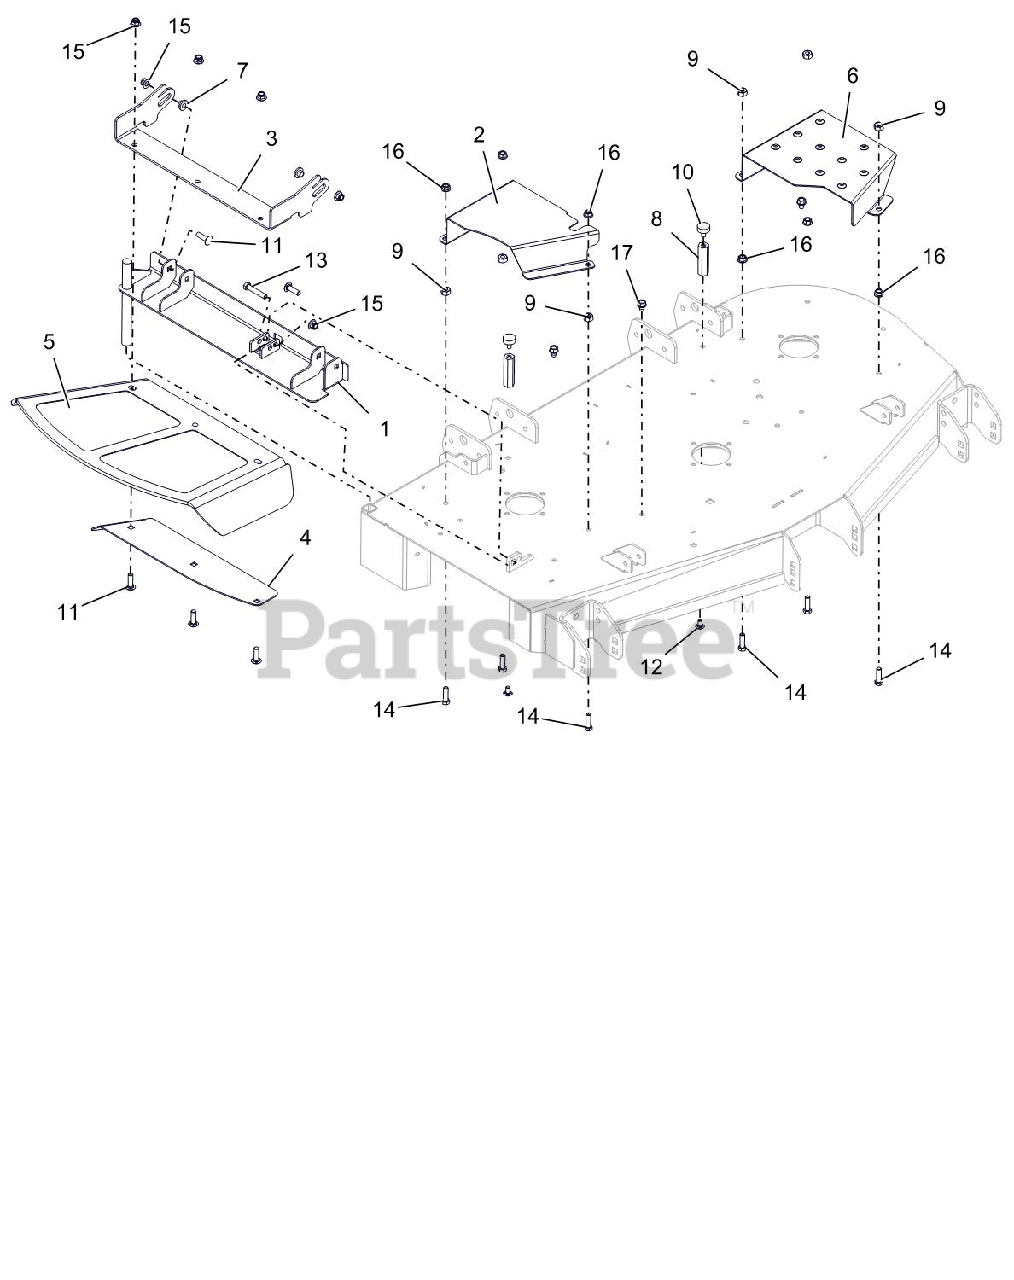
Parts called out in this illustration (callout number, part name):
1	48-60 DISCH CHT MTG WMT W/SAFE
2	GUARD,PRO-TURN DECK RH BELT-RD
3	48-60" CHUTE MTG BRKT - RED
4	48-60 DISCH CHUTE CLMP PLT-RED
5	CHUTE,48-60" FRMD RUBBER DISCH
6	GUARD,PRO-TURN DECK LH BELT-RD
7	BSHG-FLG .385X.500X.875X.406
8	NUT, COUPLING .31-18 2.75 LG
9	NUT-HEAVY HEX .38-16 YWZC
10	BUMPER, RUBBER
11	@BLT-RHDSSQNK .38-16X1.25 G5YZ
12	BLT-RDHDSQSHNK.31-18X.62 YZ-LK
13	@BLT-HEX .38-16X2.00 GR5 YWZC
14	@BLT-HEX .38-16X1.25 GR5 YWZC
15	@NUT-LK-NYL-FLG .38-16 YWZC
16	@NUT-SPNLK-FLG .375-16 YWZC
17	@SCR-TAP .38-16X.50 HWH TR YWZ
